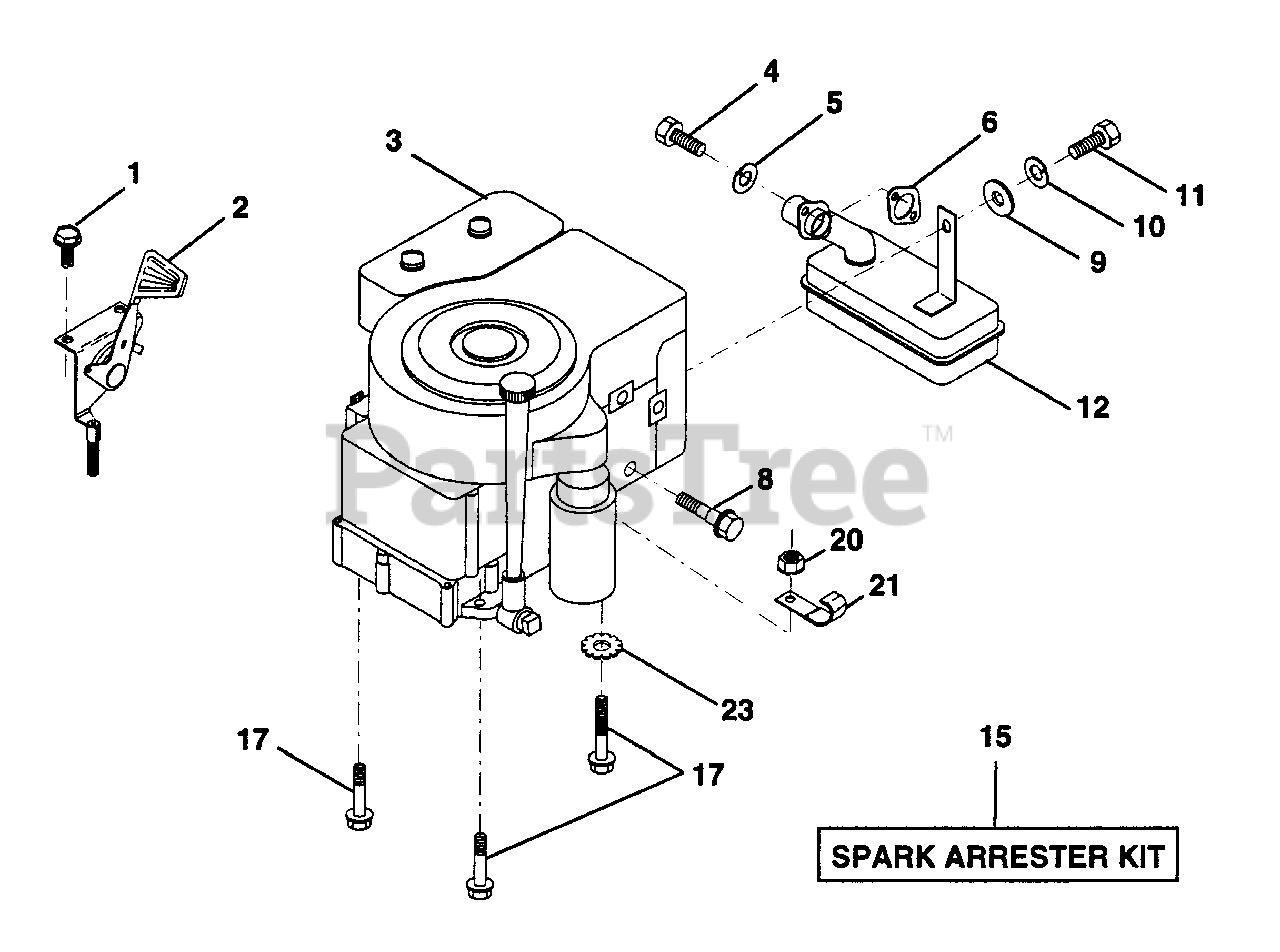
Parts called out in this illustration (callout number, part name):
1	Screw, Hex Head, Thread Cutting 1 /4-20 x 1 /2
2	Control, Throttle
3	Engine, Briggs & Stratton, 12 HP
4	Screw, Hex Cap Hd. 5/16-18 x 3/4
5	Washer, Lock, Heavy Helical Spring 5/16
6	Gasket, Exhaust
8	Bolt, Shoulder 5/16
9	Washer 5/16 x 3/4 x 16 Gauge
10	Washer, Lock, Heavy Helical Spring 1 /4
11	Bolt, Hex, Fin.
15	Arrester, Spark
17	crew, Hex Washer Head, Thd., Roll. 3/8-16 x 1-1/2
20	Nut, Hex, Keps 3/8-16
21	Clip, Fuel Line
23	Washer, Lock Ext. Tooth 3/8
